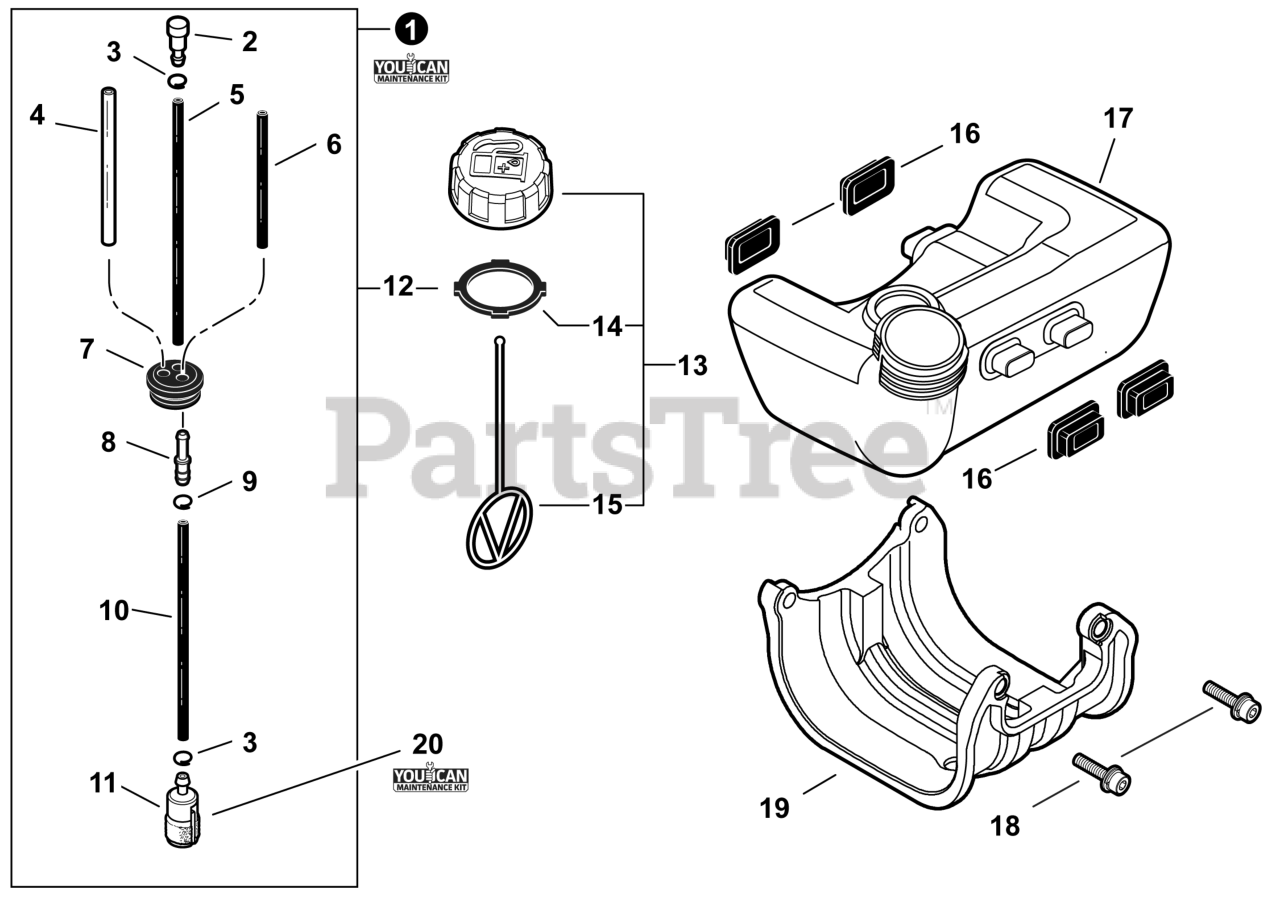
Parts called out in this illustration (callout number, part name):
1	FUEL SYSTEM KIT - YOUCANT
2	VENT ASSY
3	CLIP Ø6
4	PIPE, FUEL 3×6×80 YELLOW
5	PIPE 3×6×90 MM
6	PIPE, FUEL - 3×5×67 - BLACK
7	GROMMET, FUEL
8	CONNECTOR, PIPE Ø5ר3.5
9	CLIP Ø6.5 MM
10	PIPE, FUEL 3×6×120 BLACK
11	FILTER, FUEL
12	GASKET, FUEL CAP
13	CAP ASSY, FUEL
14	GASKET, FUEL CAP
15	CONNECTOR, CAP L= 123
16	CUSHION, FUEL TANK
17	TANK, FUEL
18	BOLT M5×20
19	GUARD, PLASTIC FUEL TANK
20	TUNE-UP KIT - YOUCANT
